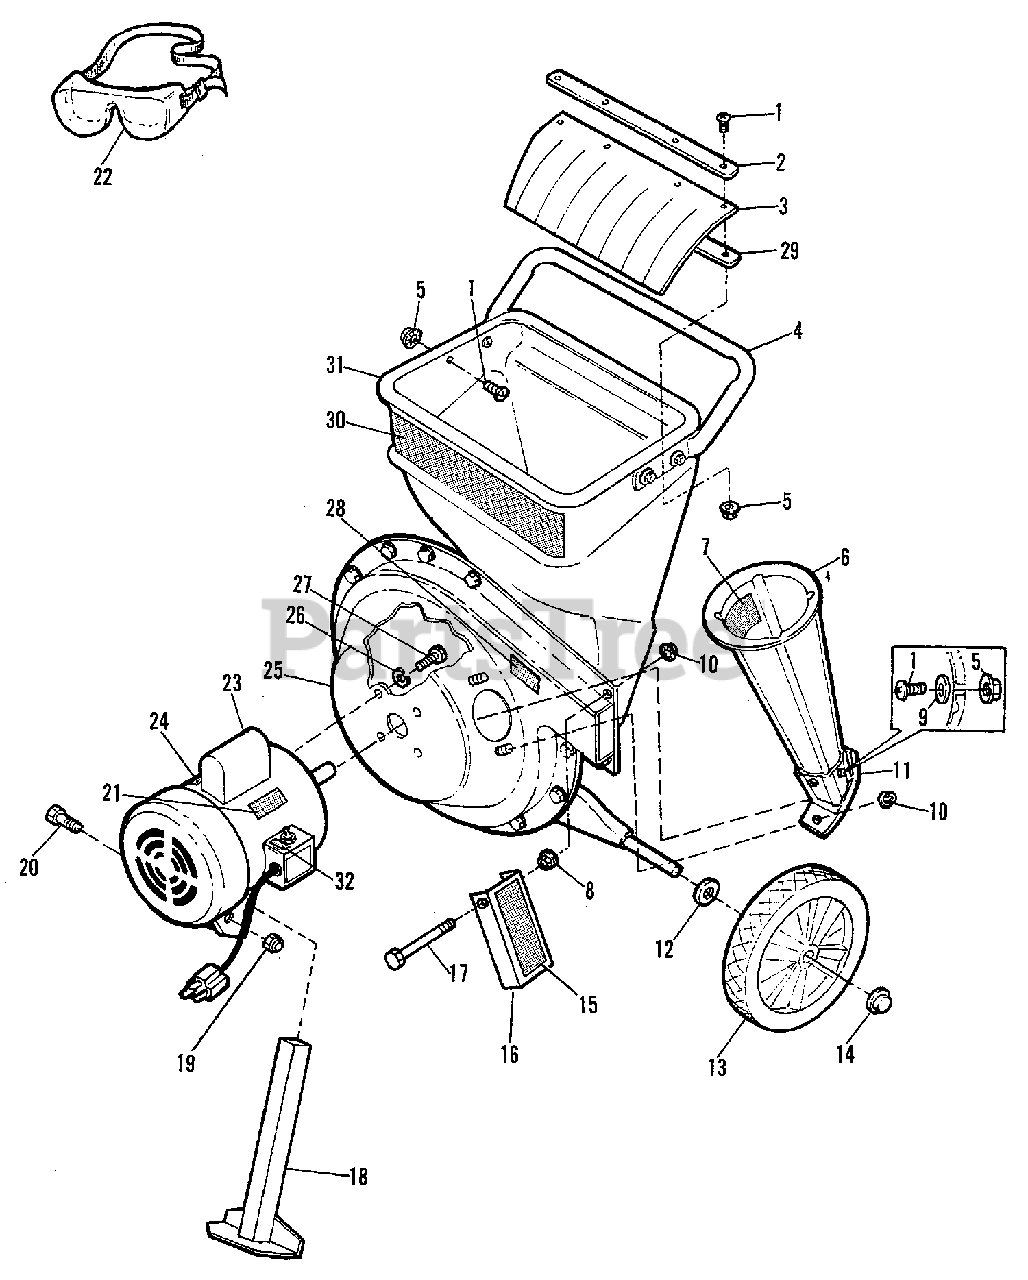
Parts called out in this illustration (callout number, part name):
1	SCREW, Button Head, Hex Socket, 1/4-20 x 3/4
2	RETAINING STRIP, Hopper Guard
3	GUARD, Hopper
4	HANDLE, Hopper
5	NUT, Flange Two Way Lock, 1/4-20
6	CHIPPER CONE
7	DECAL, Danger
8	NUT, Shoulder
9	WASHER, 1/4"
10	NUT, Whiz, 5/16-18
11	CHIPPER CONE CASTING
12	WASHER, 1/2"
13	WHEEL, 1-3/4 x 12
14	PUSH NUT, 1/2"
15	DECAL, Danger
16	DISCHARGE DEFLECTOR
17	BOLT, Shoulder
18	LEG TUBE ASSEMBLY
19	NUT, ESNA, 5/16-18
20	CAPSCREW, Hex Head, 5/16-18 x 1-3/4
21	DECAL, Caution-Motor
23	MOTOR ASSEMBLY, 1-1/2 HP Electric
24	DECAL, Danger-Motor
25	CHIPPER HOUSING
26	LOCKWASHER, 3/8"
27	CAPSCREW, Hex Head, 3/8-16 x 5/8
29	SUPPORT, Hopper Guard
31	SHREDDER HOPPER
32	DECAL, On-Off
